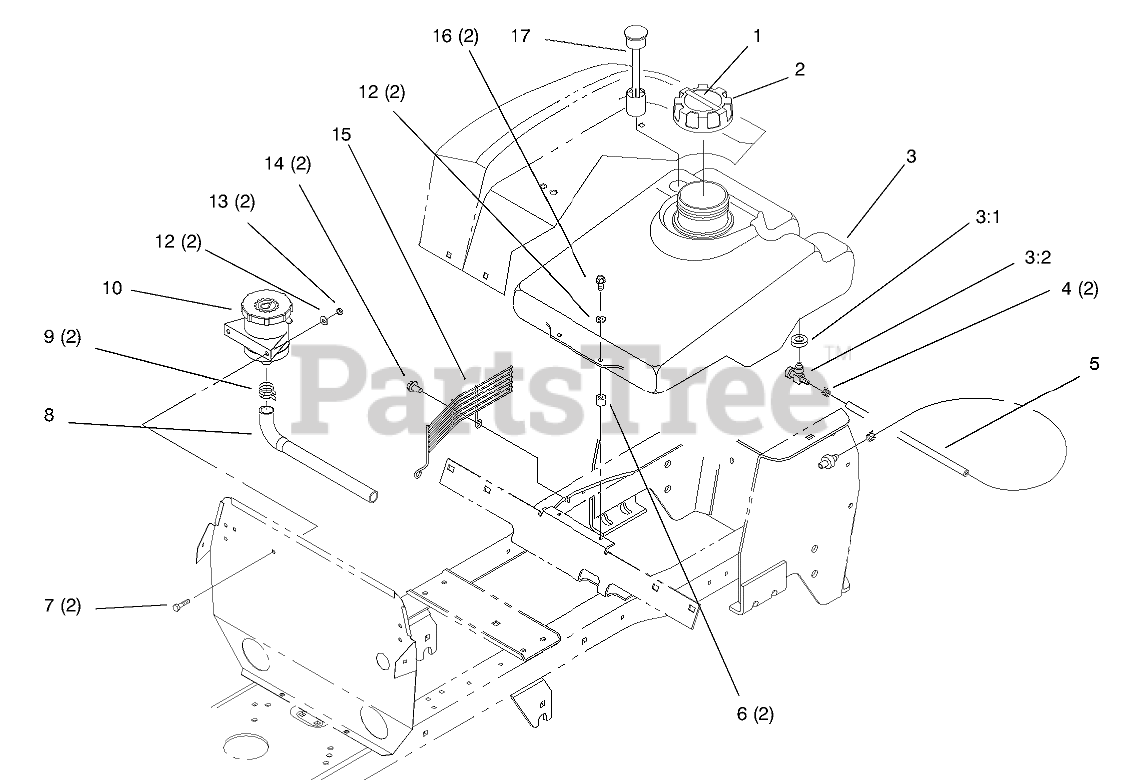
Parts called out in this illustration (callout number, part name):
2	GAS CAP ASM
3	TANK-GAS
3:1	BUSHING
3:2	VALVE-FUEL
4	CLAMP-HOSE
5	HOSE - FUEL LINE
16	SCREW-HWH
